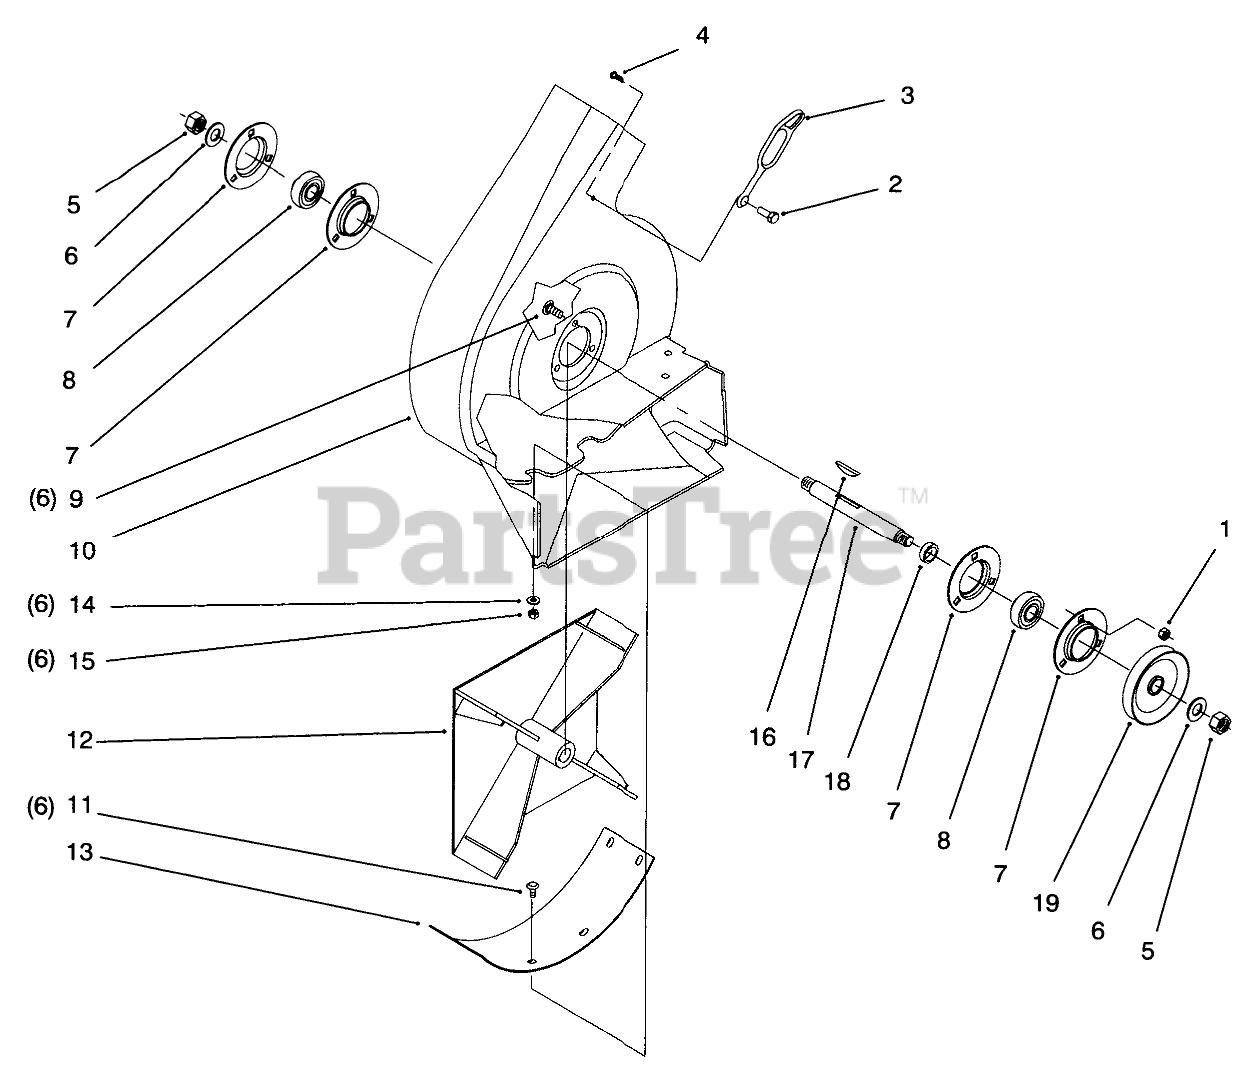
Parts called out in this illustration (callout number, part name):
1	NUT-HF
2	FASTENER-PANEL
3	RETAINER-DUCT
4	SPACER-INTERLOCK
5	NUT-JAM
6	WASHER-LOCK
7	FLANGE
8	BEARING-BALL
9	SCREW-CARR
10	TUBE-PIVOT, HANDLE
11	SCREW-CARRIAGE
12	Impeller
13	COVER-BLOWER, BOTTOM
14	WASHER-FLAT
15	NUT-LOCK, NI
17	SHAFT-BLOWER
18	Spacer
19	PULLEY-BLOWER
